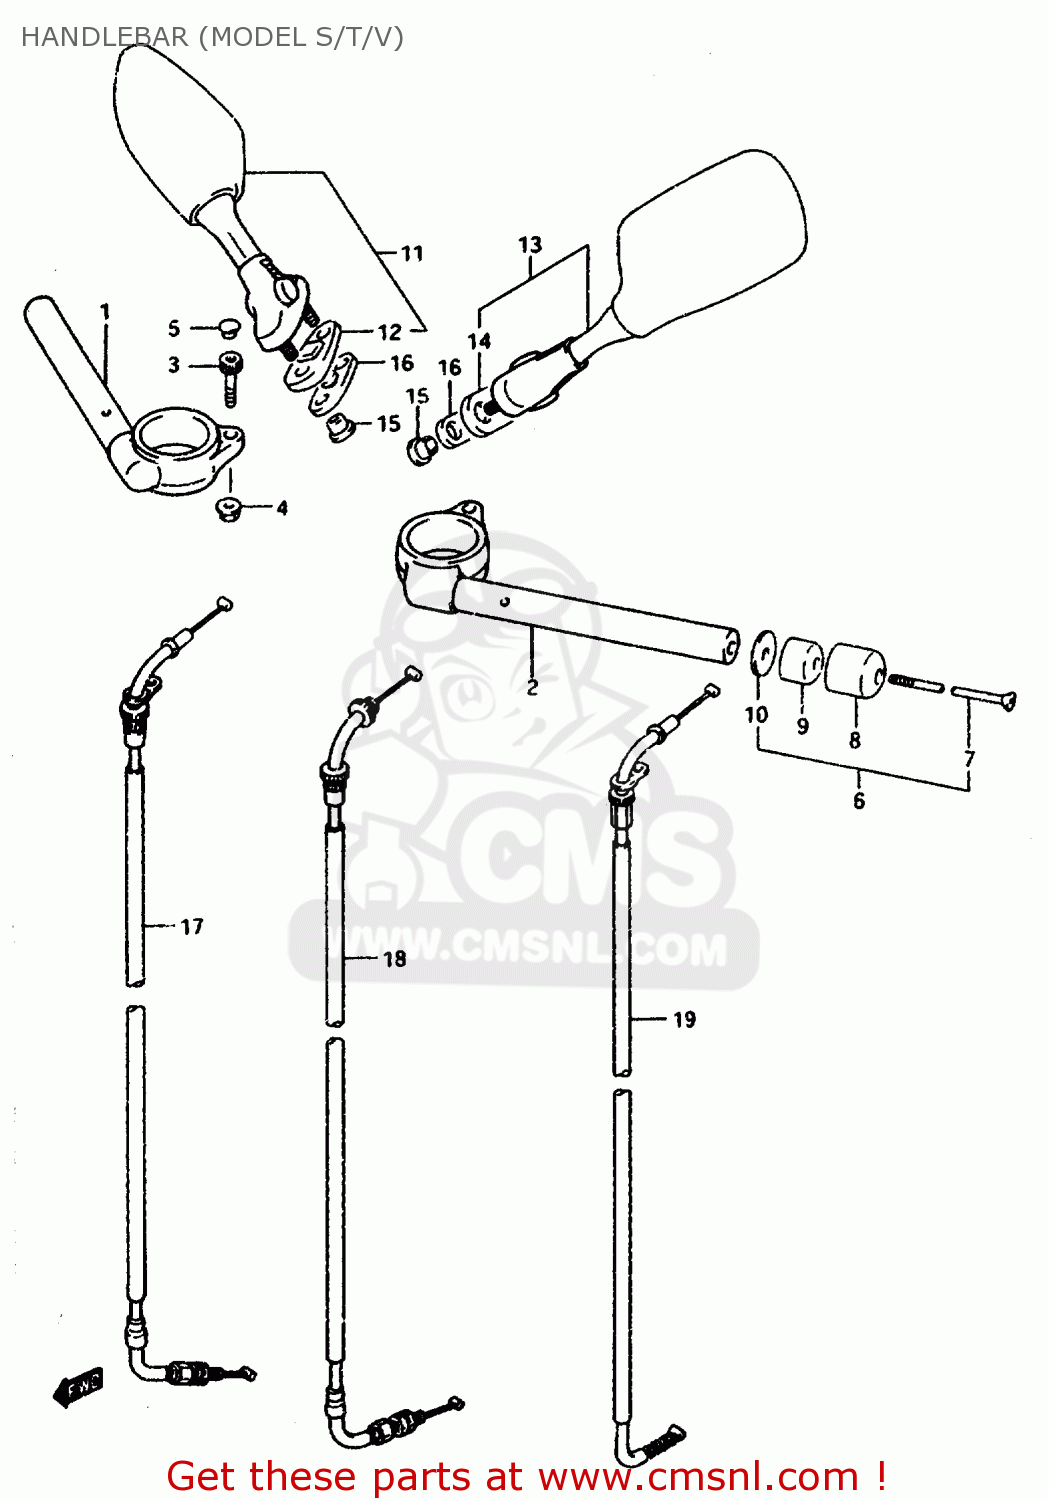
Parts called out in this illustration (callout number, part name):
1	HANDLEBAR,R
2	HANDLEBAR,L
3	BOLT
4	NUT
5	CAP(OD:12)
6	BALANCER SET,HANDLEBAR
7	SCREW
8	CAP,HANDLE BALANCER
9	BALANCER,HANDLEBAR
10	SPACER,BALANCER
11	MIRROR ASSY,RR VIEW,R
12	GASKET,RR VIEW MIRROR,R (NAS)
13	MIRROR ASSY,RR VIEW,L
14	GASKET,RR VIEW MIRROR,L (NAS)
15	NUT,RR VIEW MIRROR
16	CUSHION,RR VIEW MIRRORR
17	CABLE ASSY,THROTTLE NO.1
18	CABLE ASSY,THROTTLE NO.2
19	CABLE,STARTER
